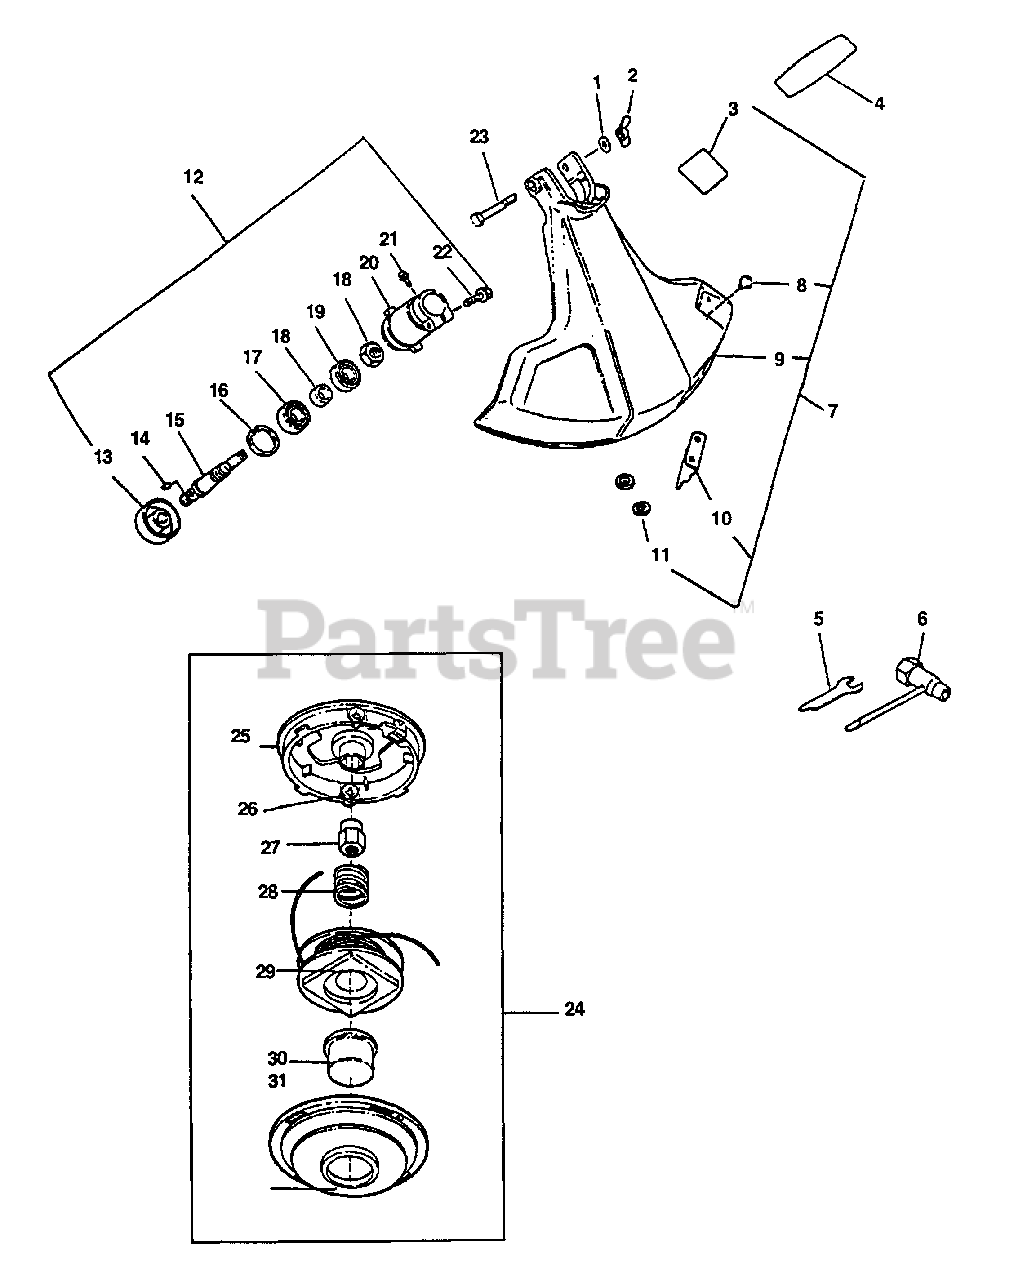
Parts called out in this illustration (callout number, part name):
1	WASHER - 6
2	WINGNUT - 6
3	LABEL - CAUTION
4	LABEL - ECHO
5	T-WRENCH - 8X19mm
6	SPANNER - 10mm
7	DEBRIS SHIELD KIT
8	SCREW - 5X16
9	SHIELD, DEBRIS - PLASTIC
10	KNIFE, TRIMMER LINE
12	GEAR CASE ASSY
13	ADAPTOR, BLADE - UPPER
14	PIN - 3X6
15	GEAR - SHAFT
16	RING, RETAINING - 28
17	BEARING, BALL - 6001 DDU
19	NUT - 12 -- LEFT HAND
20	CASE, GEAR
21	SCREW - 4X10
22	BOLT - 5X25
23	BOLT - 6X50
23	BOLT - 1/4-20 X 2"
24	KNIFE, TRIMMER LINE
25	HOUSING
26	EYELET
27	BOLT
28	SPRING
29	SPOOL ASSY
30	BUTTON
31	COVER
